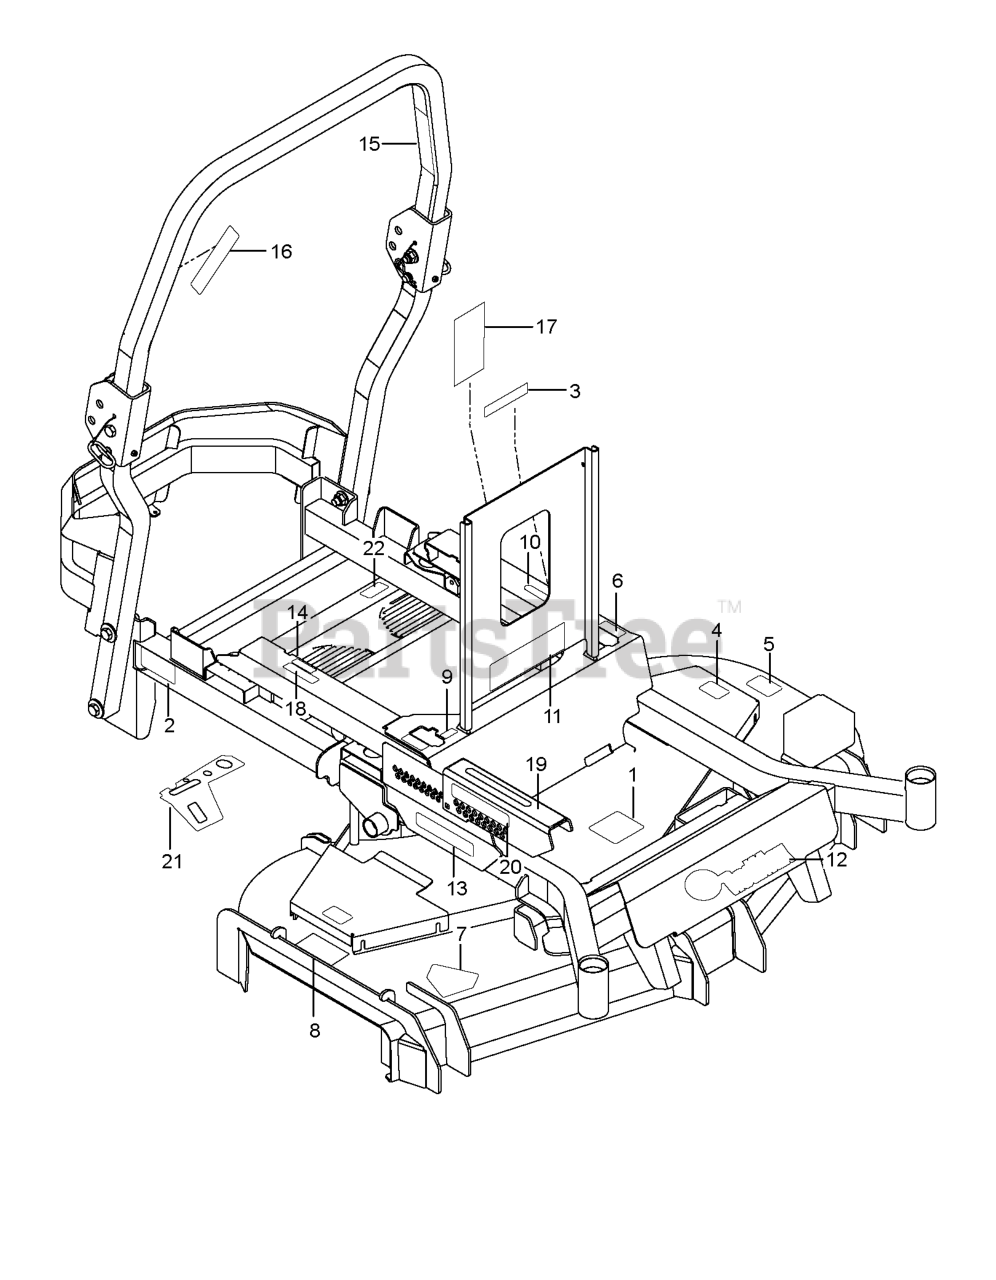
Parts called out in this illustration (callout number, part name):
1	DECAL, BELT ROUTING
2	DECAL, BELT DRIVE
3	EURO DECAL-BATTERY WARNIN6
4	DECAL.DECK.6MIL.EURO.NOSTEP
5	DECAL DECK DECAL DECAL.DECK.54
6	DECAL.ZTR.MTNCONTROL.2015.PPRO
7	DECAL, DECK DEFLECTOR, WARNING
8	DECAL.DECK.6MIL./DEF.SHLD.WARN
9	DECAL.ZTR.TRACKING.GRAPHIC
10	DECAL.ZTR.TRACKING.GRAPHIC
11	DECAL ZTR WARNING DECAL DECAL.
12	DECAL ZTR BRAND GRAPHIC DECAL.
13	DECAL ZTR SIDE RAIL GRAPHIC DE
14	DECAL ZTR INSTRUCTION GRAPHIC
15	DECAL, ROPS
16	DECAL, ROPS, WARNING
17	DECAL, SERVICE
18	DECAL, WARNING SPARK ARRESTOR
19	DECAL ZTR INSTRUCTION GRAPHIC
20	DECAL ZTR INSTRUCTION GRAPHIC
21	DECAL ZTR CONTROL PANEL DECAL.
22	DECAL ZTR INSTRUCTION GRAPHIC
